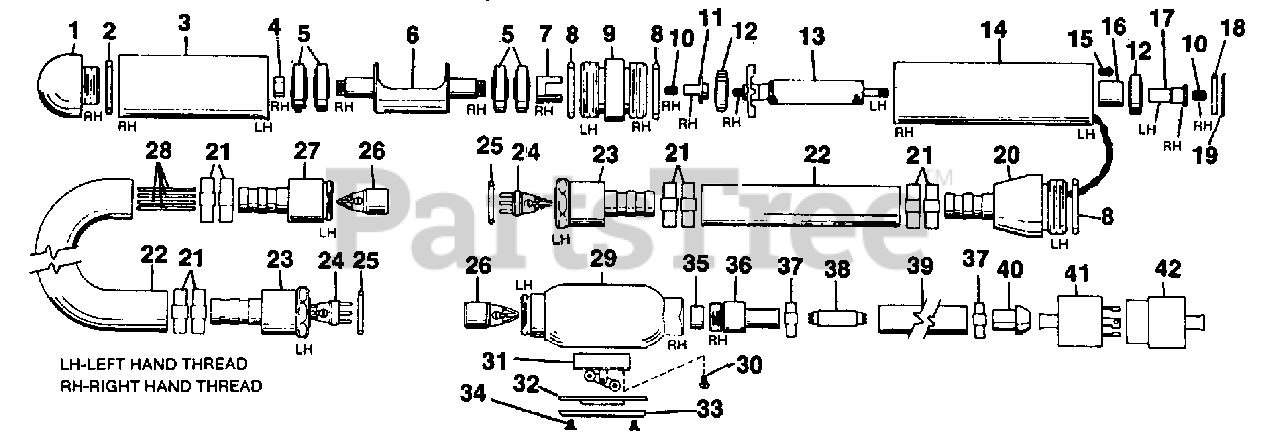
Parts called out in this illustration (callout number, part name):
1	NOSE- Steel
3	BARREL- Eccentric
6	ECCENTRIC
7	DRIVER- Female
9	CONNECTOR- Center
10	SCREW- Set
11	DRIVER- Male
12	BEARING-Motor
14	MOTOR BARREL & STATOR
17	SHAFT- Extension
18	SPACER- Bearing
19	RING- Snap
20	CONNECTOR- Hose
21	CLAMP- Hose
23	CONNECTOR- Female
26	RECEPTACLE
27	CONNECTOR- Male
29	SWITCH BOX
33	COVER- Switch Box
36	CONNECTOR- Cable
37	CLAMP- Hose
39	HOSE- Protective
40	FITTING- Hose end cone
41	PLUG- "Twist lock"
42	RECEPTACLE-"Twist lock"
